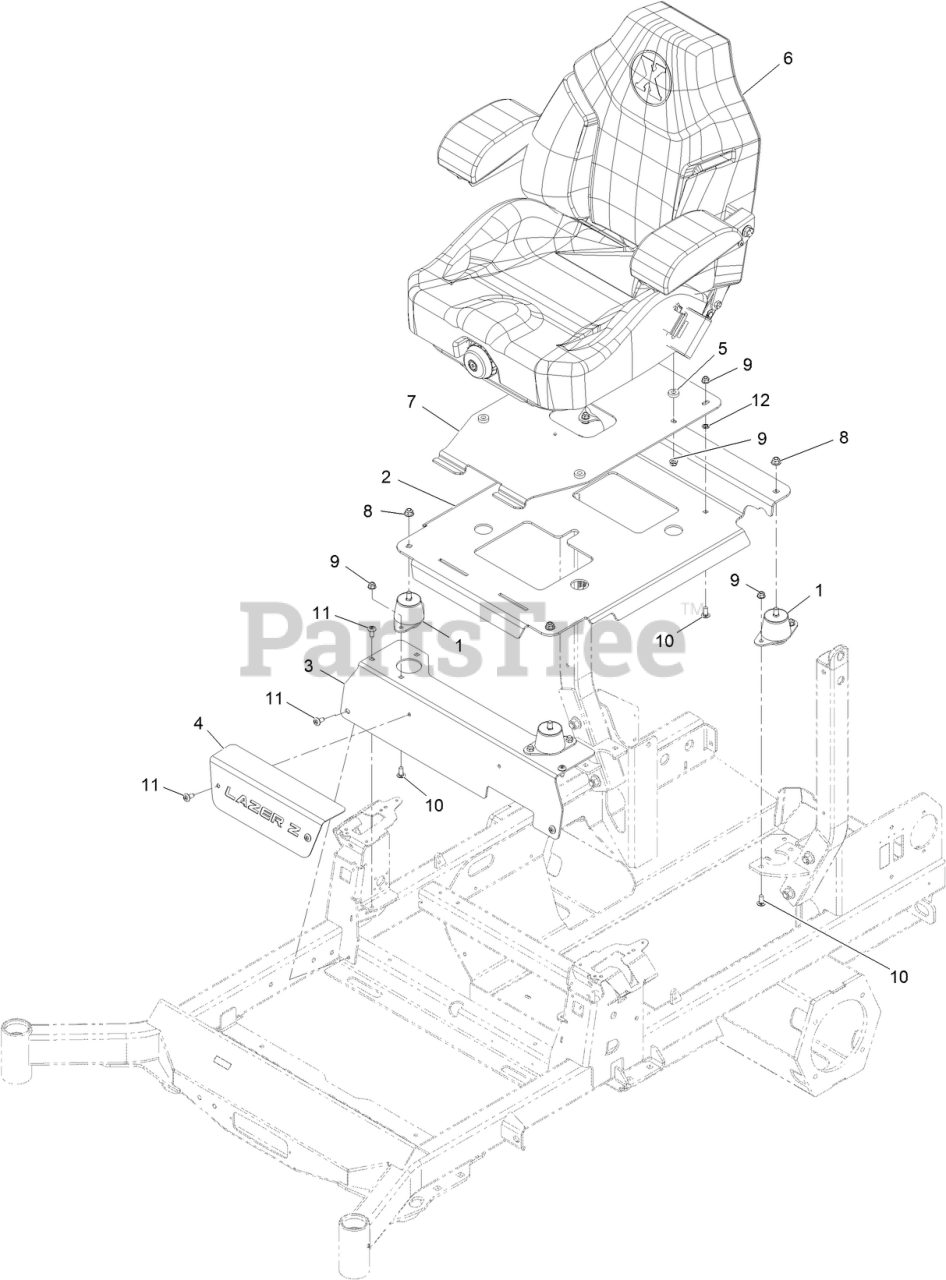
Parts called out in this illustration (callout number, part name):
1	ISOLATOR-SEAT
2	Panel-Seat ISO
3	Plate-Heel
4	Plate-Accent Heel
5	SPACER
6	ASM-SUSPENSION SEAT
8	NUT-HF, NI
9	NUT-HF, NI
10	SCREW-CARR
12	NUT-PUSH
